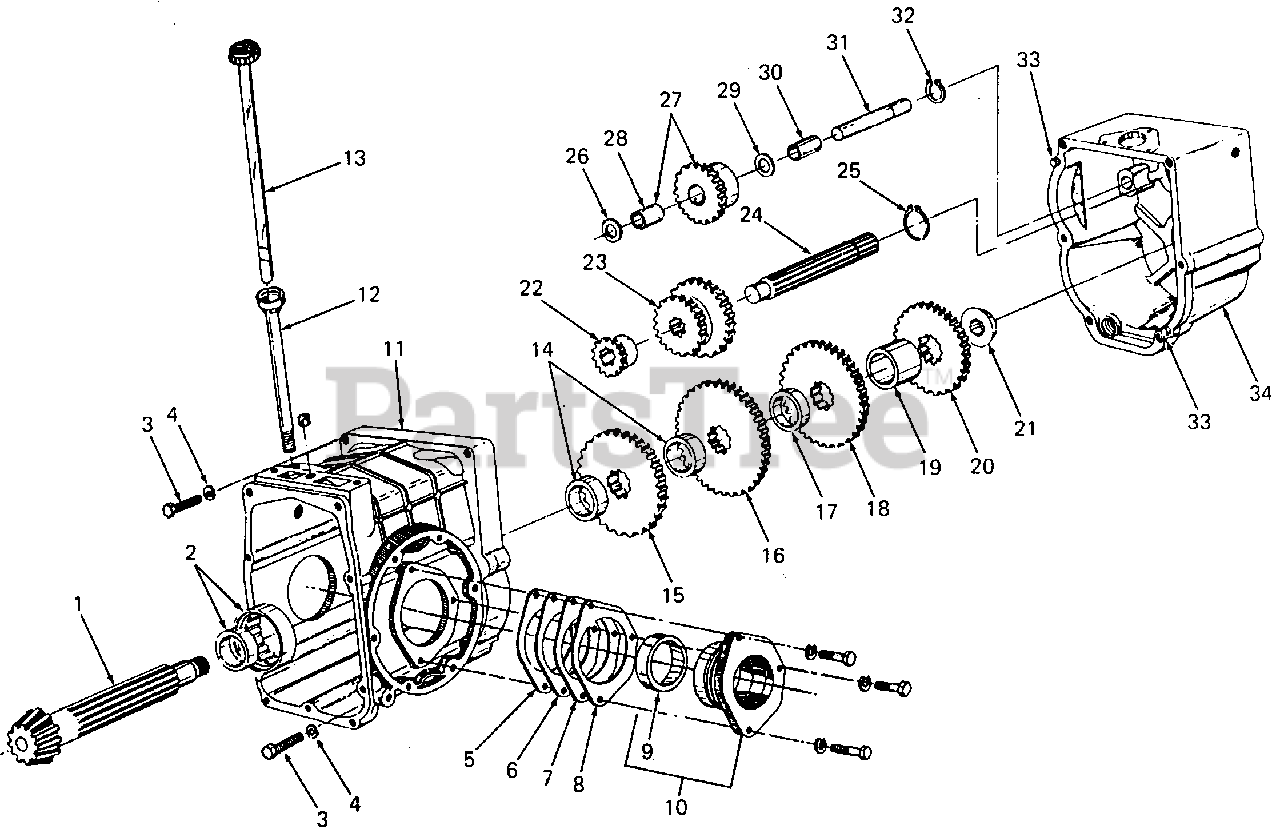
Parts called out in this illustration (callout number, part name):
1	Shaft, Pinion - 10T
2	Bearing Assy, Roller
3	Screw, Hex Cap, 7/16-14 X 1.75 Lg GR5
4	Washer, Spring, .445 X .75 X .017 Thk
5	Shim, Bearing Retainer, .004 Thk
6	Shim, Bearing Retainer, .007 Thk
7	Shim, Bearing Retainer, .014 Thk
8	Shim, Bearing Retainer, .028 Thk
9	Cup, Roller Bearing
10	Retainer Assy, Bearing w/Cup
11	Housing Assy, Rear w/Needle Brg
12	Tube, Dipstick
13	Blade Assy, Dipstick
14	Spacer, 1.18 X 1.75 X .692 Lg
15	Gear, Reverse - 35T
16	Gear, 1st Speed - 39T
17	Spacer, 1.18 X 1.75 X .312 Lg
18	Gear, 2nd Speed - 35 T
19	Spacer, 1.18 X 1.75 X 1.312 Lg
20	Gear, 3rd Speed - 26T
21	Spacer, .788 X 1.75 X .375 Lg
22	Gear, Sliding, 1st & Rev Speed - 13T
23	Gear, Sliding 2nd & 3rd Speed - 17 & 26T
24	Shaft, Main
25	Ring, Snap
26	Spacer, 5/8 ID X .220 Lg
27	Gear Assy, Reverse - 22T
28	Bearing, Sleeve, .6125 ID X 1.125 Lg
29	Washer, Flat
30	Sleeve, .629 X .750 X 1.81 Lg
31	Shaft, Reverse Idler
32	Ring, Retaining
33	Pin, Dowel, .38 Dia X .62 Lg
34	Housing, Gear
